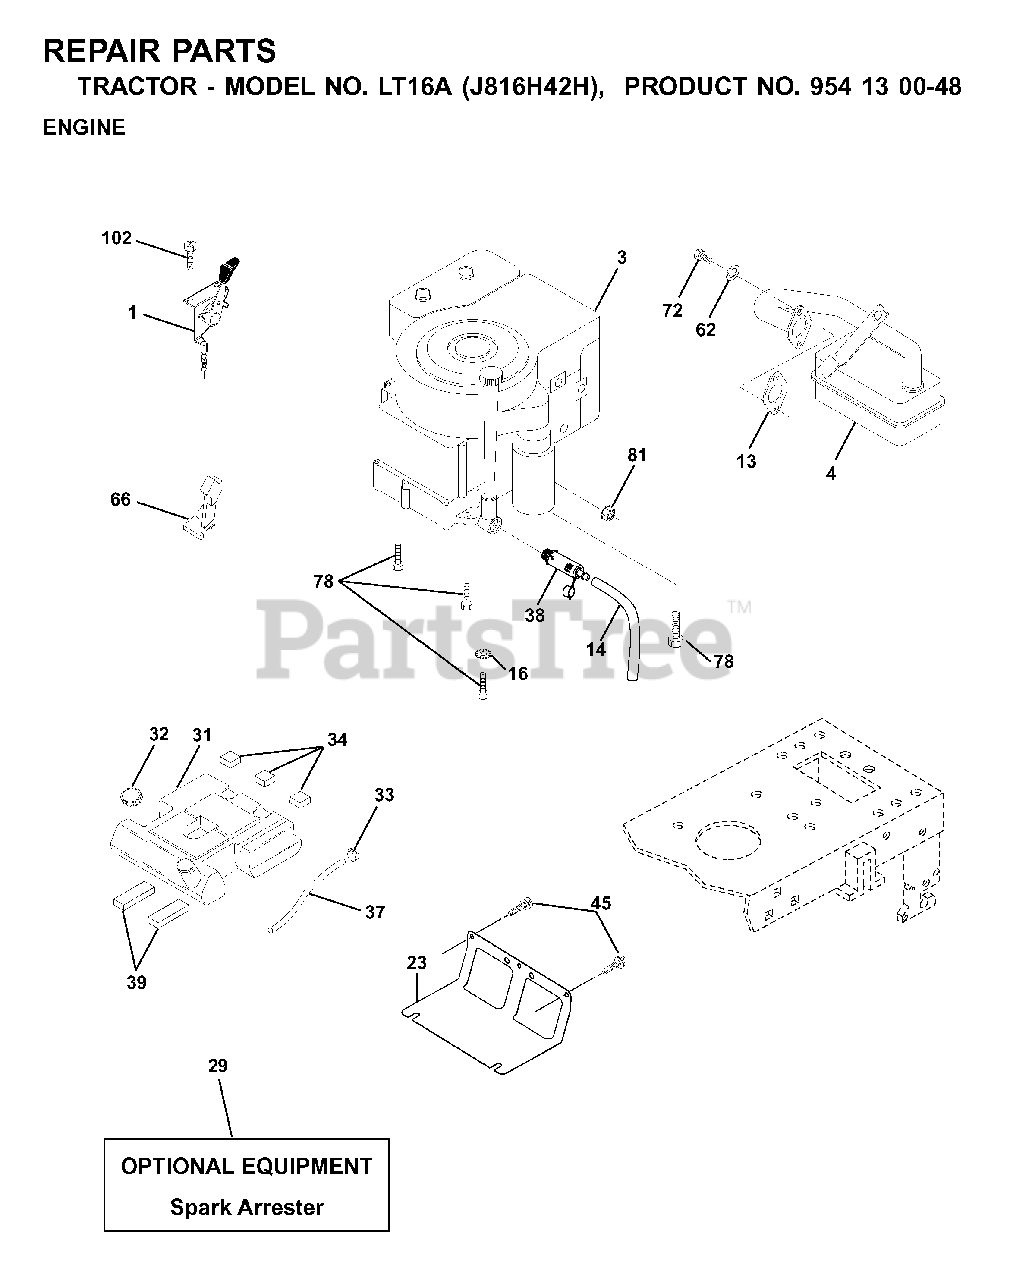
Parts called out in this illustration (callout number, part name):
13	REPL BY 532 27 22-93
14	TUBE, DRAIN OIL ASM.
16	LOCKWASHER
23	SHEILD.BROWNING.DBR.GUARD
29	ARRESTER SPARK (OPTIONAL)
31	TANK.FUEL(3.5.GAL)
32	FUEL CAP
33	HOSE CLAMP
34	PAD-SPACER LT
38	PLUG, OIL DRAIN EASY
39	PAD IDLER TI
45	SCREW, 3/8-16X3/4
62	LOCKWASHER
66	STOP THROTTLE
72	SCREW
78	SCREW.3/8-16
81	NUT
102	SCREW
